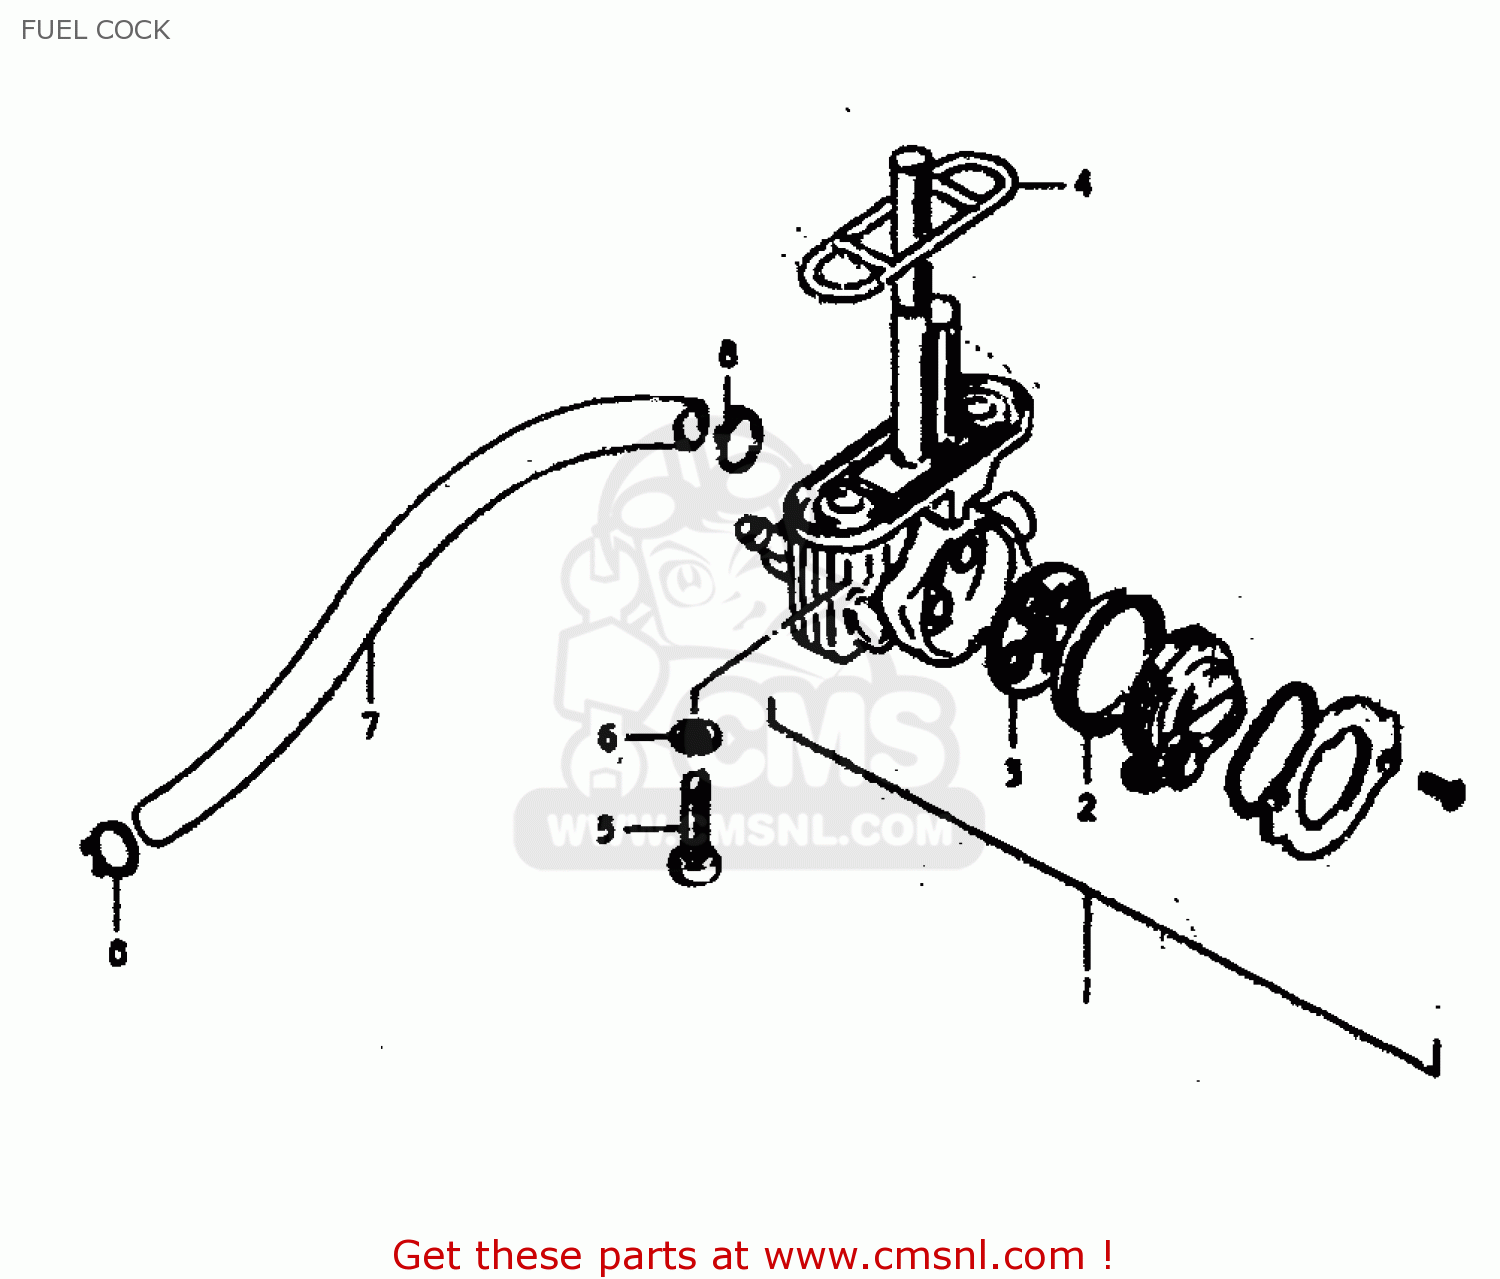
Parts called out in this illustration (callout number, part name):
1	COCK ASSEMBLY,FUEL
2	V SEAL,FUEL COCK
3	GASKET (NAS)
4	GASKET,FUEL COCK (NAS)
5	BOLT(6X20)
6	GASKET
7	HOSE
8	CLIP
